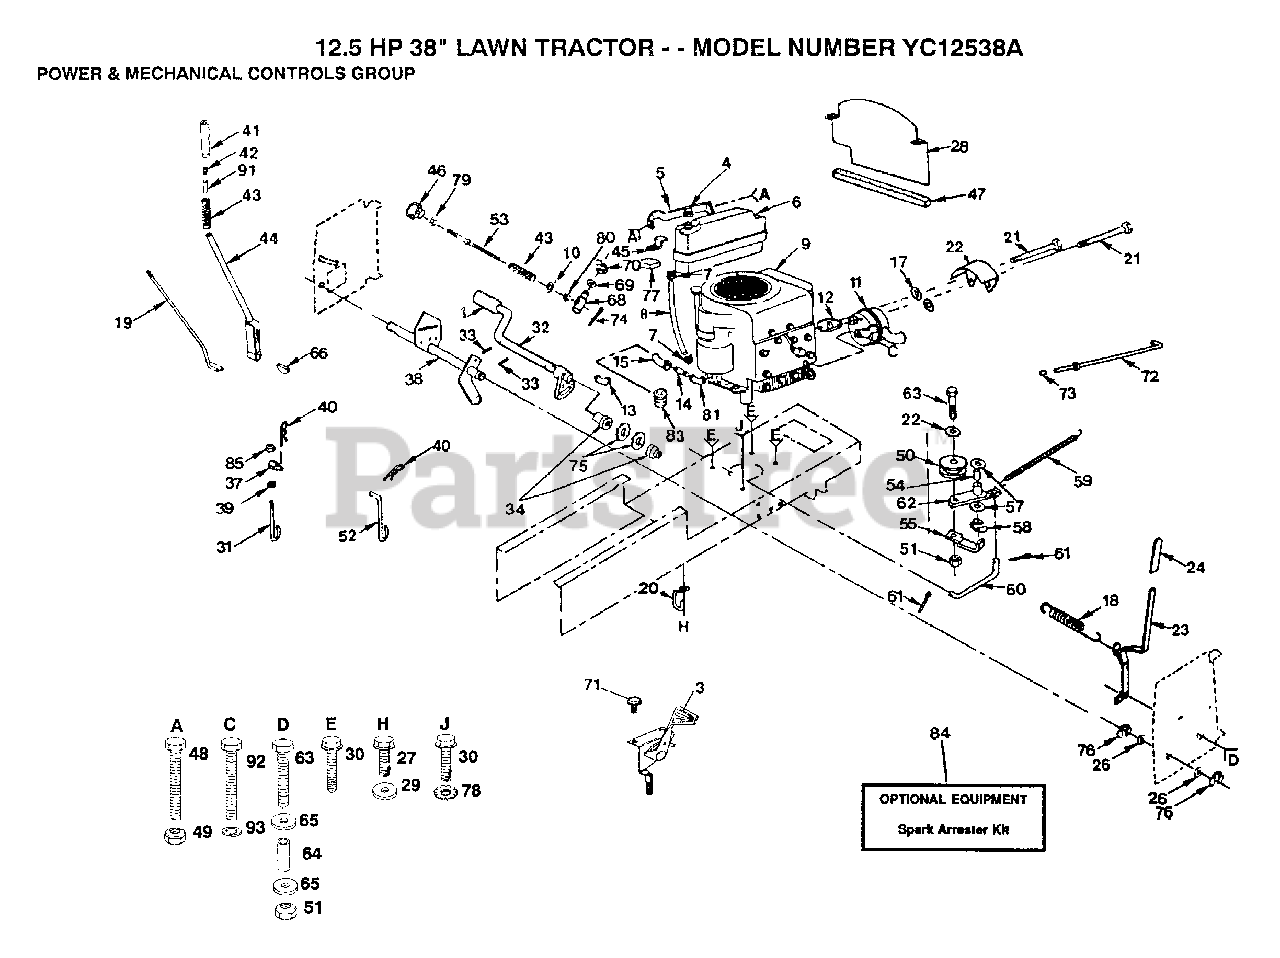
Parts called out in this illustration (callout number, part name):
1	PEDAL COVER T
5	SUPT TANK FUEL
6	FUEL TANK
7	HOSE CLAMP
8	HOSE T
10	WASHER
11	MUFFLER
13	STREET ELBOW LT
14	PIPE NIPPLE
15	ELBOW
18	"SPRING.EXT.8.5"""
19	ROD ASS'Y LEVER
21	BOLT
22	WASHER
26	WASHER
27	SCREW
29	WASHER
30	SCREW
31	PIVOT PIN T
34	NYLON BEARING
39	NUT
41	GRIP
43	SPRING T
45	BRACE-TANK LT
46	HDLE ADJ LIFT
48	BOLT
52	LIFT LINK LT
53	ROD LIFT LT
54	"LY, BEARING"
55	RETAIN BELT
57	WASHER LT
58	KLIP RING
59	"SPRING, RETURN LT"
60	"LINK, CLUTCH T"
61	COTTER PIN
62	ARM IDLER
68	TRUNION LT
69	WASHER
70	KLIP RING
71	SCREW LT
72	ROD BRAKE PARK
73	PLUNGER CAP T
75	WASHER LT
76	E-RING
77	PAD-SPACER T
78	LOCKWASHER
79	NUT
80	NUT T
81	STREET ELBOW LT
84	SPARK ARREST KIT
88	HEAT SHIELD
92	BOLT
93	LOCKWASHER
